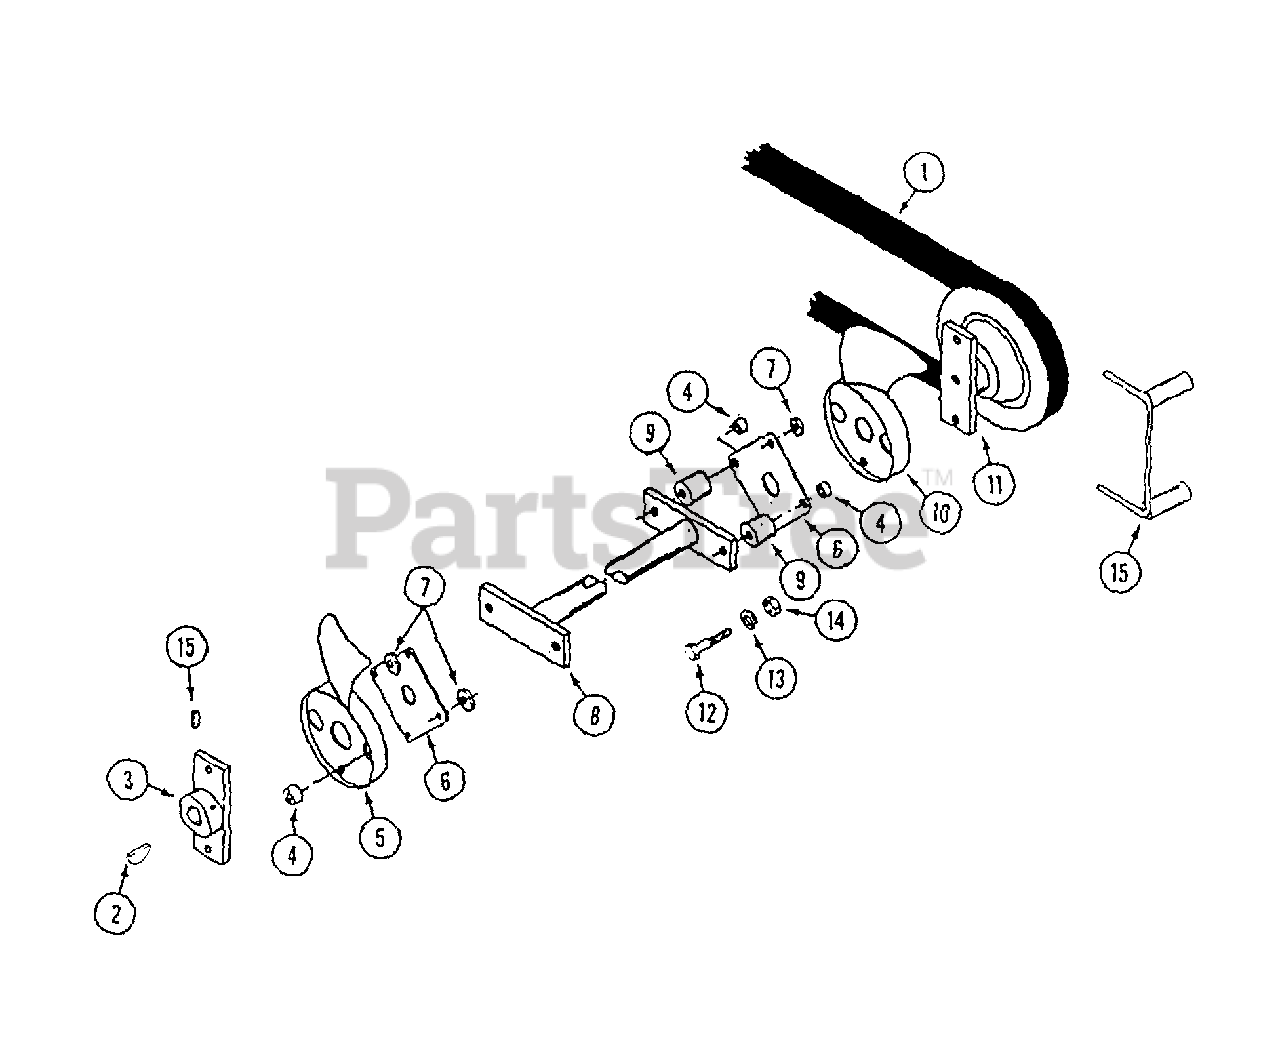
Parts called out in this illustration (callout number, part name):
1	BELT - transmission drive
2	KEY - woodruff 1/8" x 1/2"
3	HUB - drive plate
6	PLATE - drive
7	WASHER - 1/4" 10 ga.
11	PULLEY - drive
12	BOLT - 5/16" - 18 x 2-1/4"
13	LOCKWASHER - 5/16"
14	NUT - 5/16" - 18
15	RETAINER - belt
